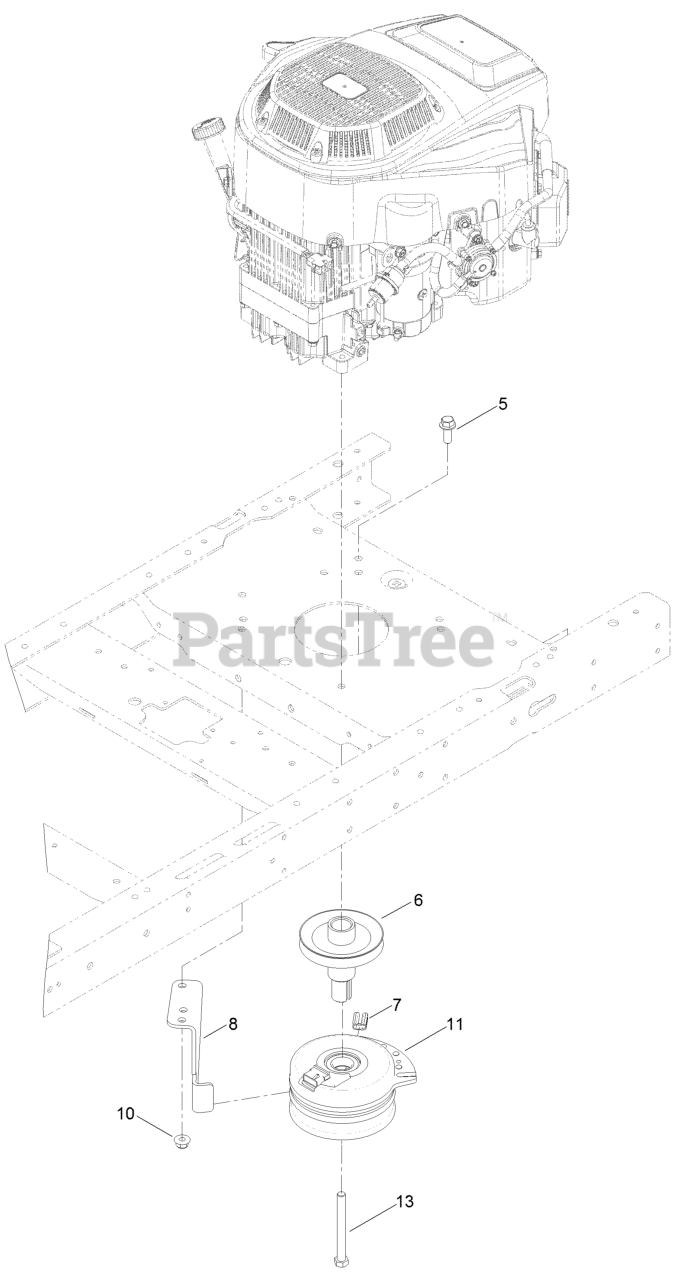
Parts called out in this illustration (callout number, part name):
5	SCREW-HHF 3/8-16 X 1
6	PULLEY-ENGINE
7	ISOLATOR-CLUTCH
8	STOP-CLUTCH (NARROW)
10	NUT-HF, NI
11	CLUTCH-ELECTRIC
13	PIN-ROLL, SLOTTED
